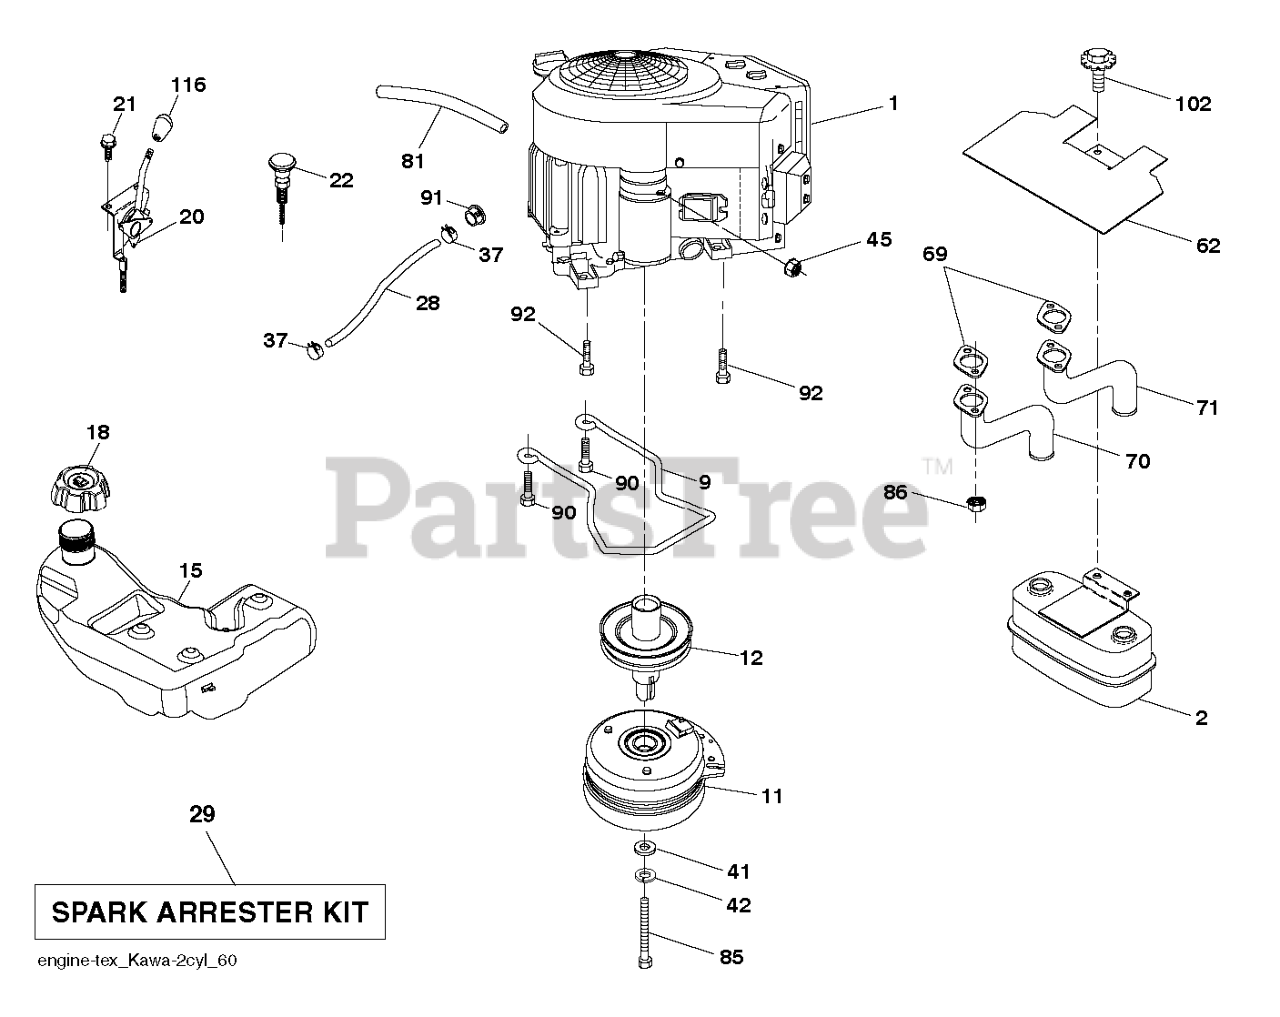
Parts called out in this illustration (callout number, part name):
2	MUFFLER.ASM.TWIN.MNTG.BRACKET
11	CLUTCH. 5.0 PD. 2.5 OFFSET
12	PULLEY.EXTENDED.SHAFT.GROUND
15	TANK ASSY W/CAP 4 GAL EPA
18	CAP ASSY FUEL 3" GRAY
18	FUEL CAP
20	CONTROL.THROTTLE.PRO.
22	CONTROL.CHOKE.ERGO.BLACK
28	HOSE 1/4" LOW PERMEATION FUEL
29	KIT.SPARK ARRESTOR 794945 B&S
37	HOSE CLAMP
62	SERVICE KIT HEAT SHIELD
70	TUBE.EXHAUST.LH.FR961/FR730
71	TUBE.EXHAUST.RH.FR961/FR730
81	TUBE, DRAIN OIL ASM.
85	BOLT.HEX.7/16-20X5.GR5.GREEN
86	NUT.HEX.FLANGE.TOPLOCK
90	SCREW 3/8-16X1
91	BUSHING.1.375OD
92	SCREW 3/8-16X1
102	BOLT.HEX.HD.WASHER.5/16-18X.75
116	KNOB - SHIFT
